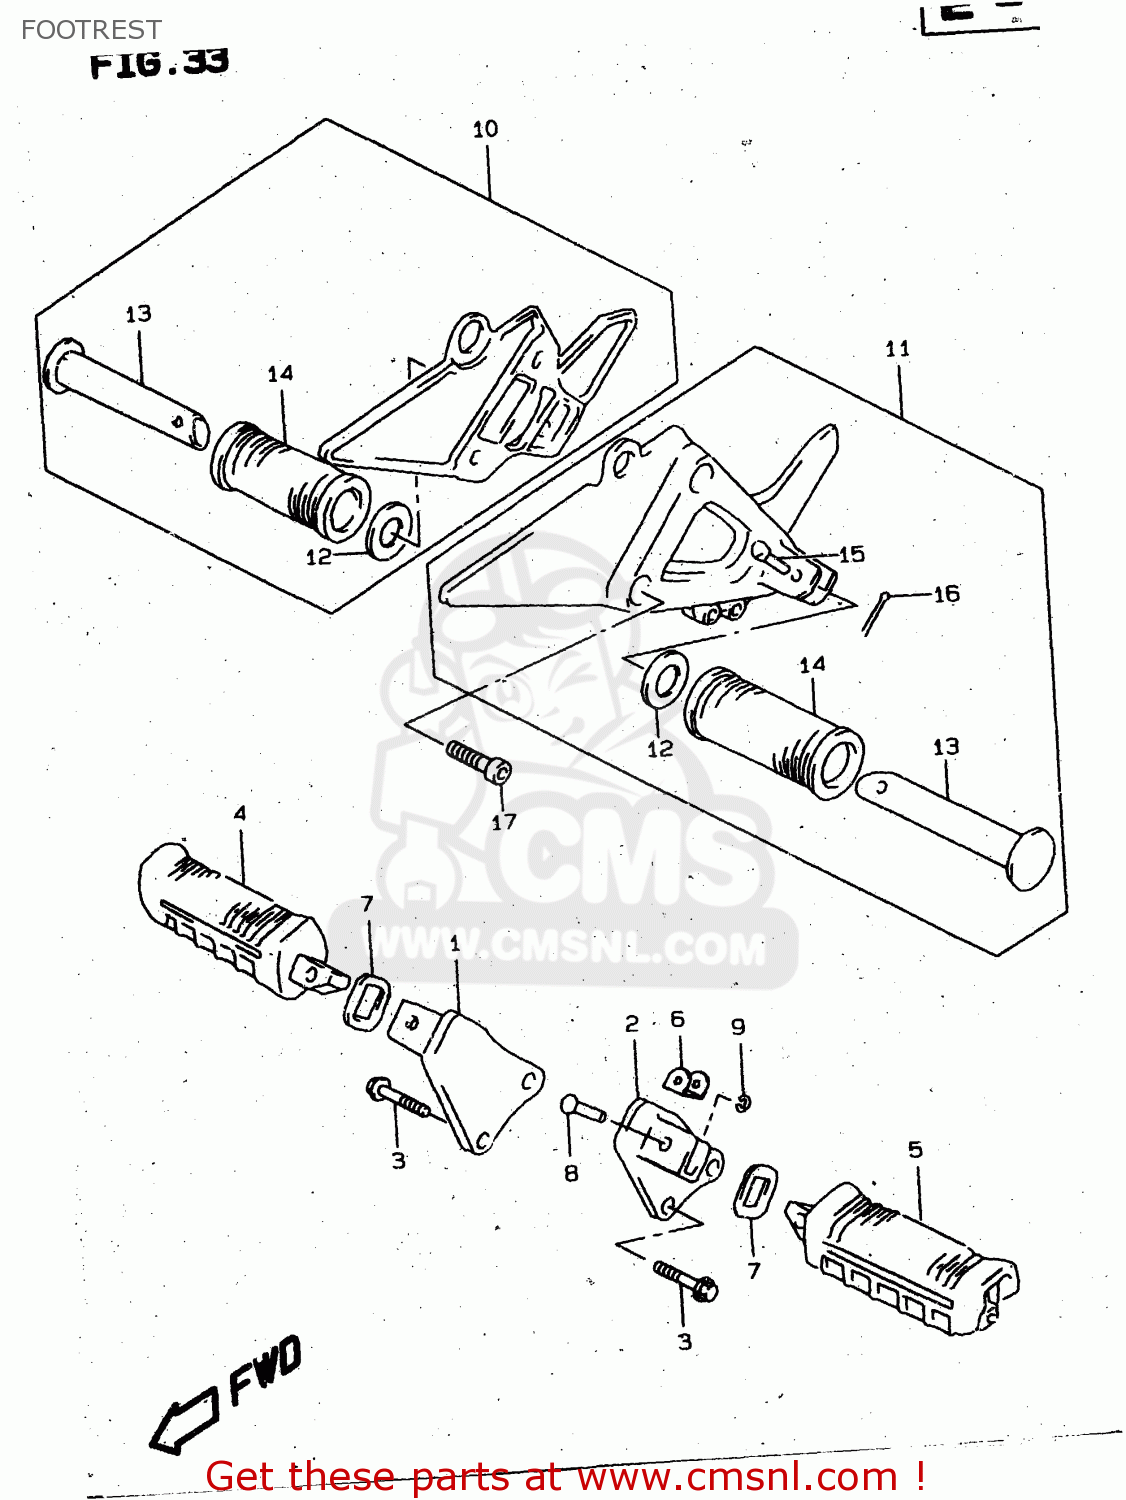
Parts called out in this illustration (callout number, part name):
1	BRACKET,FR FOOTREST,R
2	BRACKET,FR FOOTREST,L
3	BOLT(10X45)
4	RUBBER,FRONT FOOTREST,RIGHT
5	RUBBER,FRONT FOOTREST,LEFT
6	CUSHION,FR FOOTREST
7	WASHER,FOOTREST RUBBER
8	PIN
9	E-RING
10	FOOTREST ASSY,PILLION,R
11	FOOTREST ASSY,PILLION,L
12	WASHER(19.5X32X2)
13	BAR,FOOTREST RUBBER
14	RUBBER,PILLION FOOTREST
15	PIN
16	PIN
17	BOLT
